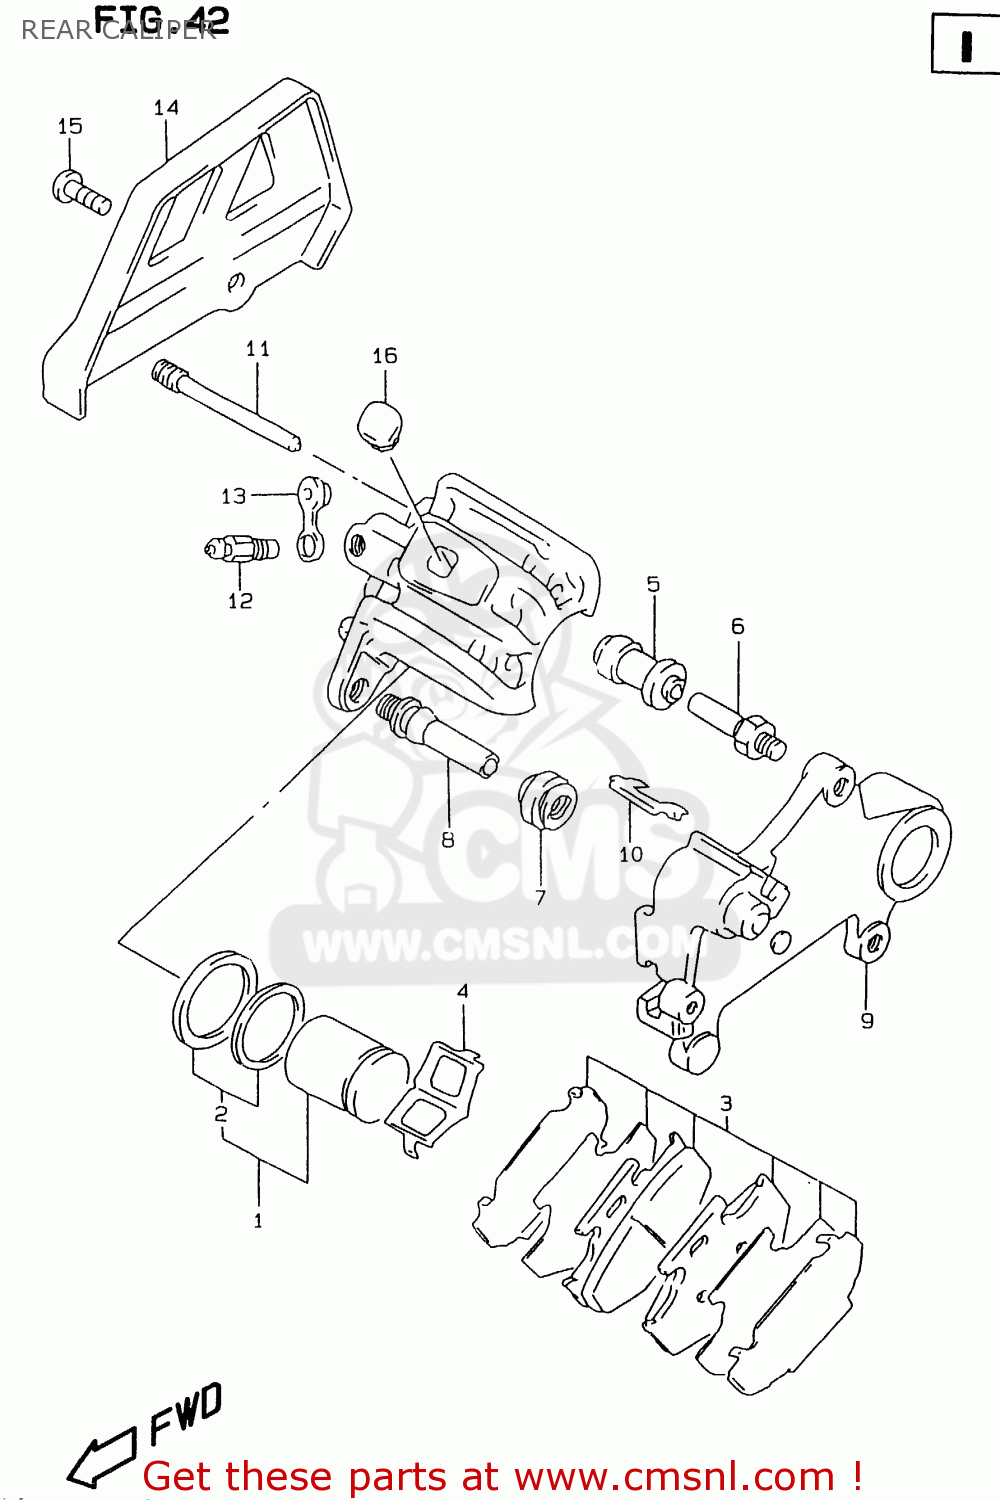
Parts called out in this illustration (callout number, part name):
1	PISTON SET
2	SEAL SET,PISTON
3	PAD & SHIM SET (NAS)
4	SPRING,PAD
5	BOOT
6	PIN,BOLT
7	BOOT
8	PIN
9	BRACKET
10	RETAINER,BRACKET
11	PIN,HANGER
12	BLEEDER
13	CAP,BLEEDER
14	GUARD SET,REAR CALIPER
15	SCREW 6X12
16	COVER,RR CALIPER BODY
